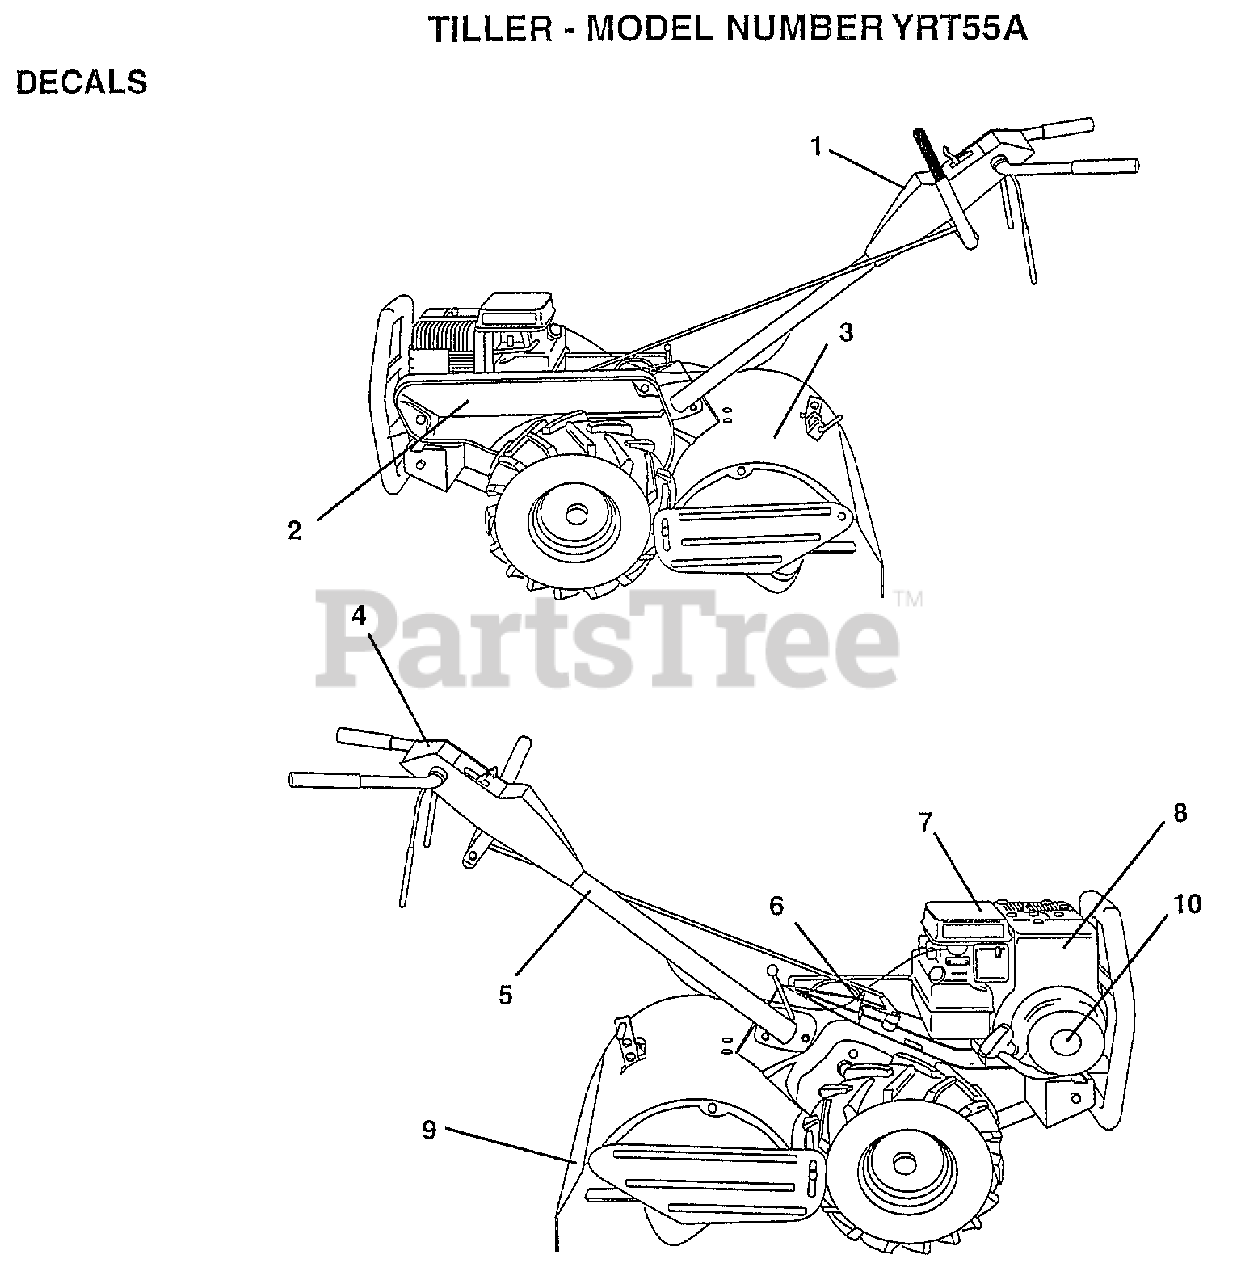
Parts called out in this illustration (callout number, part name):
1	DECAL PANEL CNTRL
2	DECAL GUARD BELT
3	DECAL SHIELD TINE
4	DECAL.INSTRUCTION
5	DECAL TI
7	DECAL TI
8	DECAL, BRIGGS & STRATTON
10	DECAL, 5.5 HP
